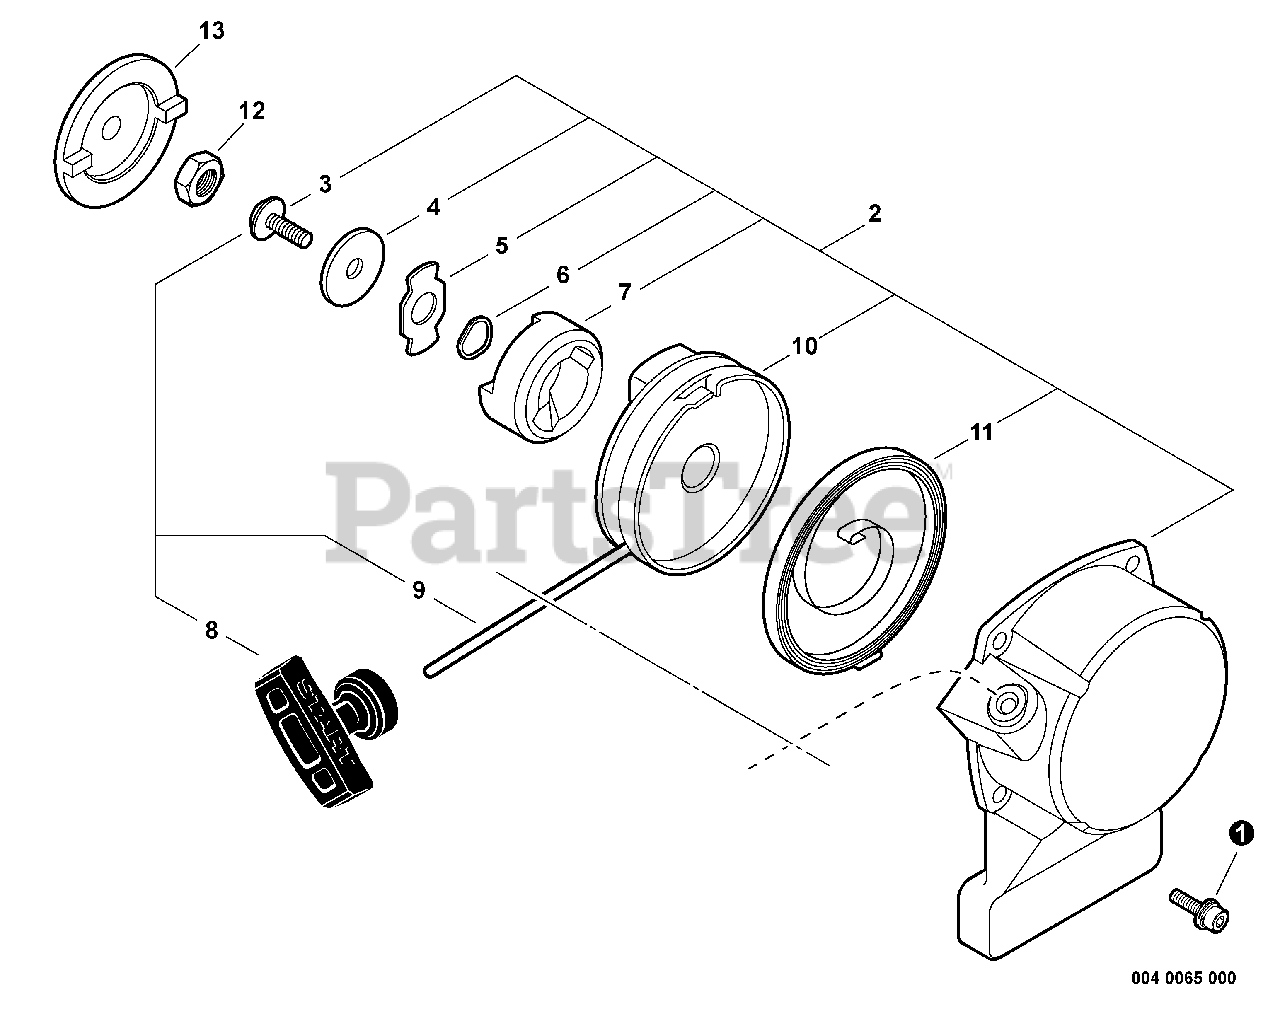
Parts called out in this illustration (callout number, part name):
1	BOLT M4×12
2	STARTER ASSY, RECOIL
3	SCREW 5 MM
4	WASHER 5 MM
5	RETAINER
6	WASHER, WAVE
7	PAWL, STARTER
8	GRIP, STARTER
9	ROPE, STARTER
10	REEL, ROPE
11	SPRING, RECOIL
12	NUT M8×1
13	PULLEY, STARTER
